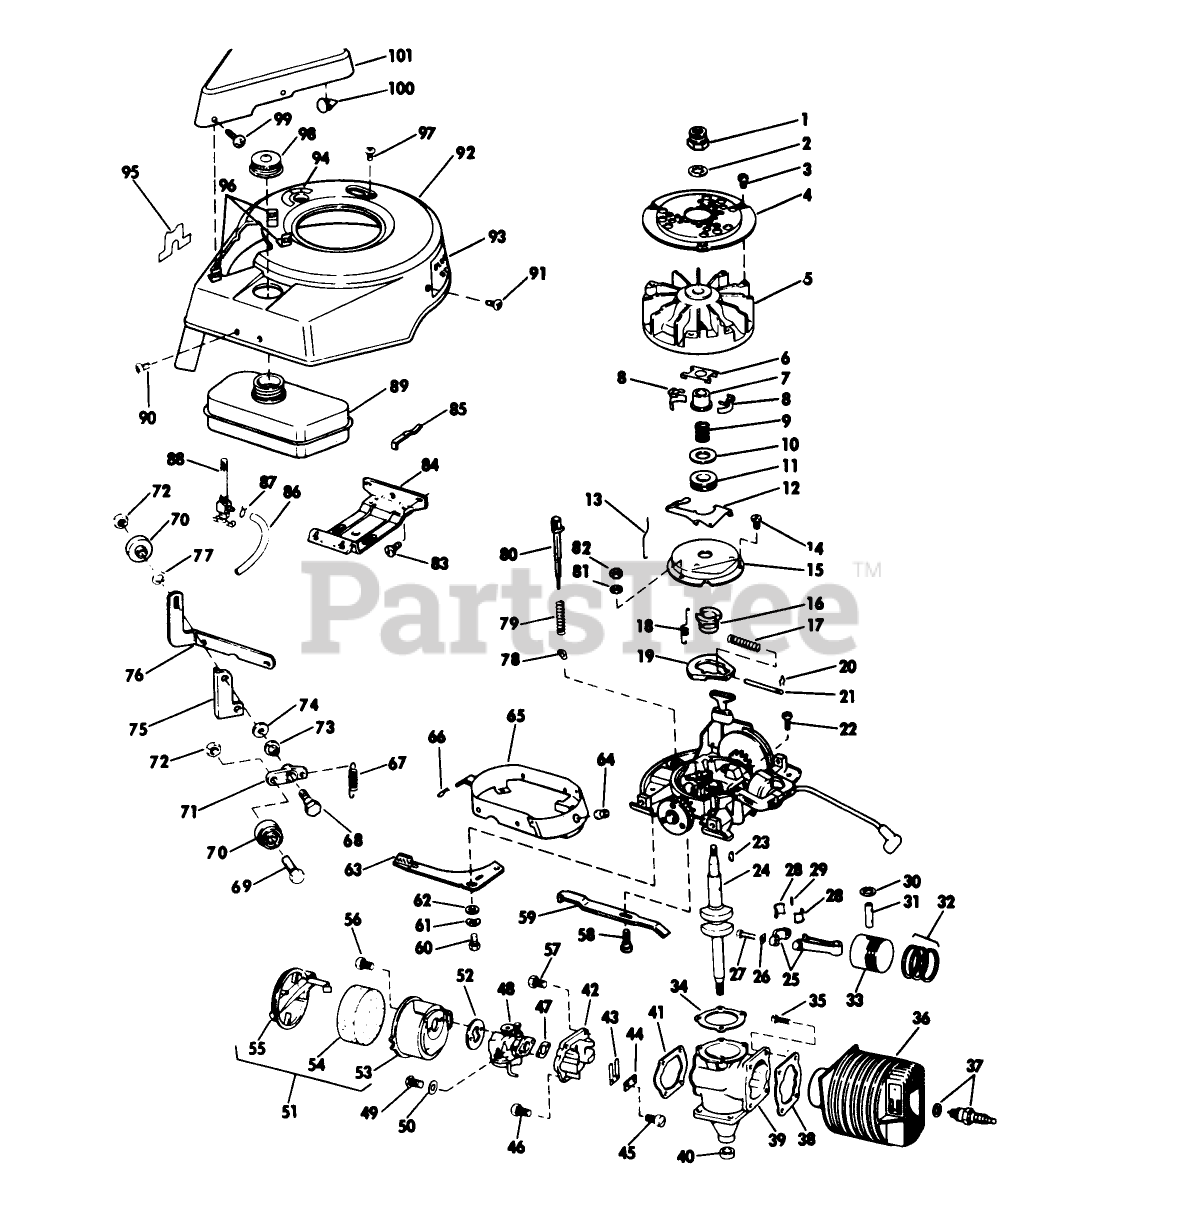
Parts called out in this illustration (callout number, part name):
7	COLLAR S
9	SPRING S
11	THRUST COLLAR S
12	LEVER-GOVERNOR S
14	SCREW S
15	DUST COVER S
16	SPARK ADV. S
17	SPARK ADV. SPRING S
19	FLYWEIGHT S
20	SPARK ADJ. SPRING
21	PIN,SPARK ADV. S
28	LINER ASM
30	RING-RETAINING
34	GASKET S
38	GASKET S
44	PLATE-BACKUP, REED
46	SCREW S
47	GASKET S
54	AIR FIL.ELEM S
56	SCREW S
57	SCREW S
64	NUT-CLIP
79	SPRING S
83	SCREW S
86	Gas Line
87	CLAMP - HOSE S
88	VALVE&SCREEN SM
91	SCREW S
